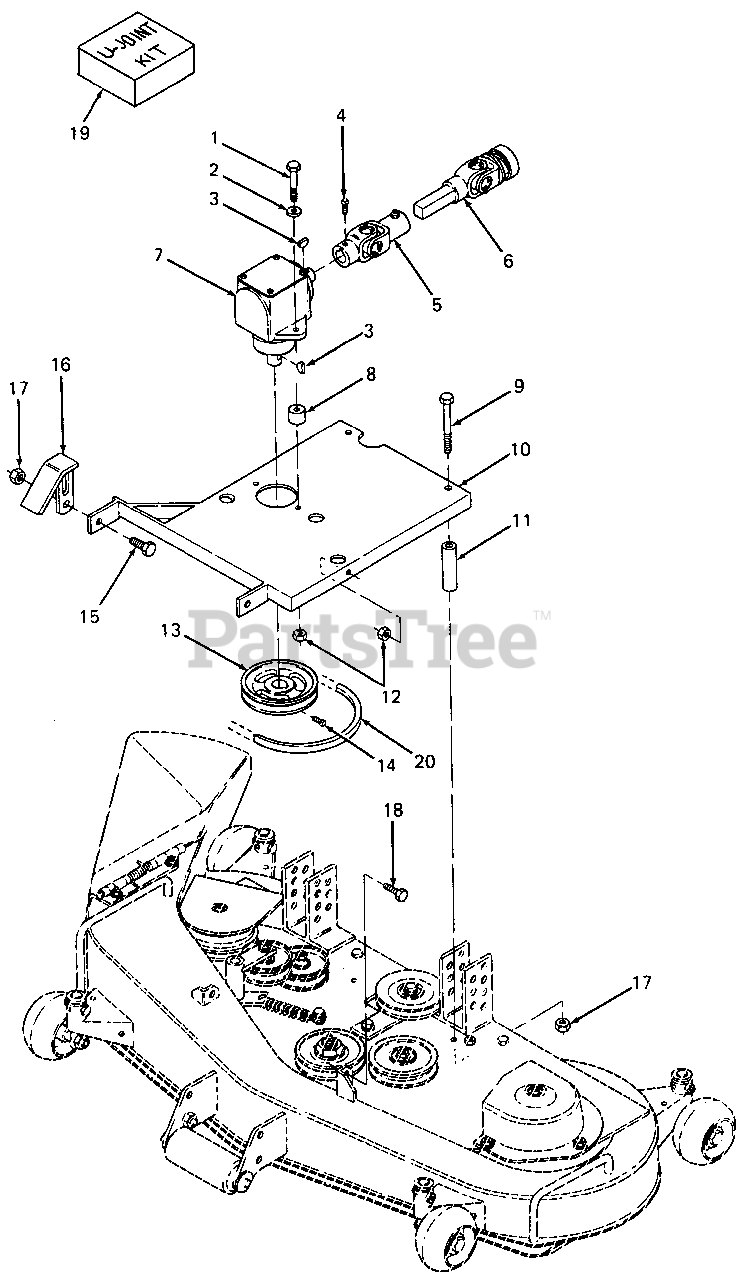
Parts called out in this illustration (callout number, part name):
1	Screw, Hex Cap, 3/8-16 X 2.0 Lg GR8
2	Washer, Flat, .406 X 1.25 X .100 Thk
3	Key, Hi-Pro, 3/16 X .75 HDN
4	Setscrew, 5/16-18 X .50 Sq Hd Cup
5	Driveshaft Assy, Female
6	Driveshaft Assy, Quick Disconnect
7	Gearbox Assy, Right Angle
8	Riser, Gearbox Mounting
9	Screw, Hex Cap, 1/2-13 X 4.0 Lg GR5
10	Plate, Mounting
11	Riser, Mounting Plate
12	Nut, Hex Center Lock, 3/8-16
13	Pulley, Gearbox
14	Setscrew, 5/16-18 X 5/8 Sq Hd Cup
15	Screw, Hex Cap, 1/2-13 X 1.0 Lg GR5
16	Hanger, Mower w/Graphic
17	Nut, Hex Center Lock, 1/2-13
18	Screw, Hex Cap, 3/8-16 X 1.0 Lg GR5
19	Kit, U-Joint
20	Belt, Short Deck
